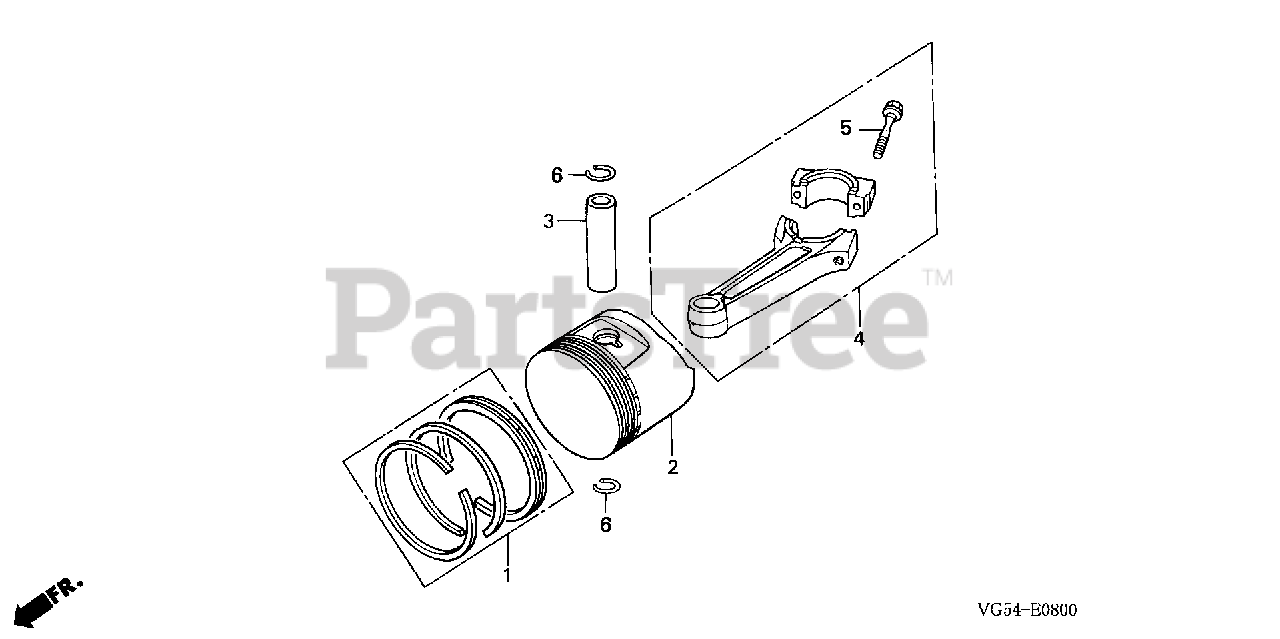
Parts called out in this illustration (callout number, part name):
1	RING SET, PISTON (STD)
1	RING SET, PISTON (OS 0.25)
1	RING SET, PISTON (OS 0.50)
1	RING SET, PISTON (0.75)
2	PISTON (STD)
2	PISTON (OS 0.25)
2	PISTON (OS 0.50)
2	PISTON (0.75)
3	PIN, PISTON
4	ROD ASSY., CONNECTING
5	BOLT, CONNECTING ROD
6	CLIP, PISTON PIN (20MM)
